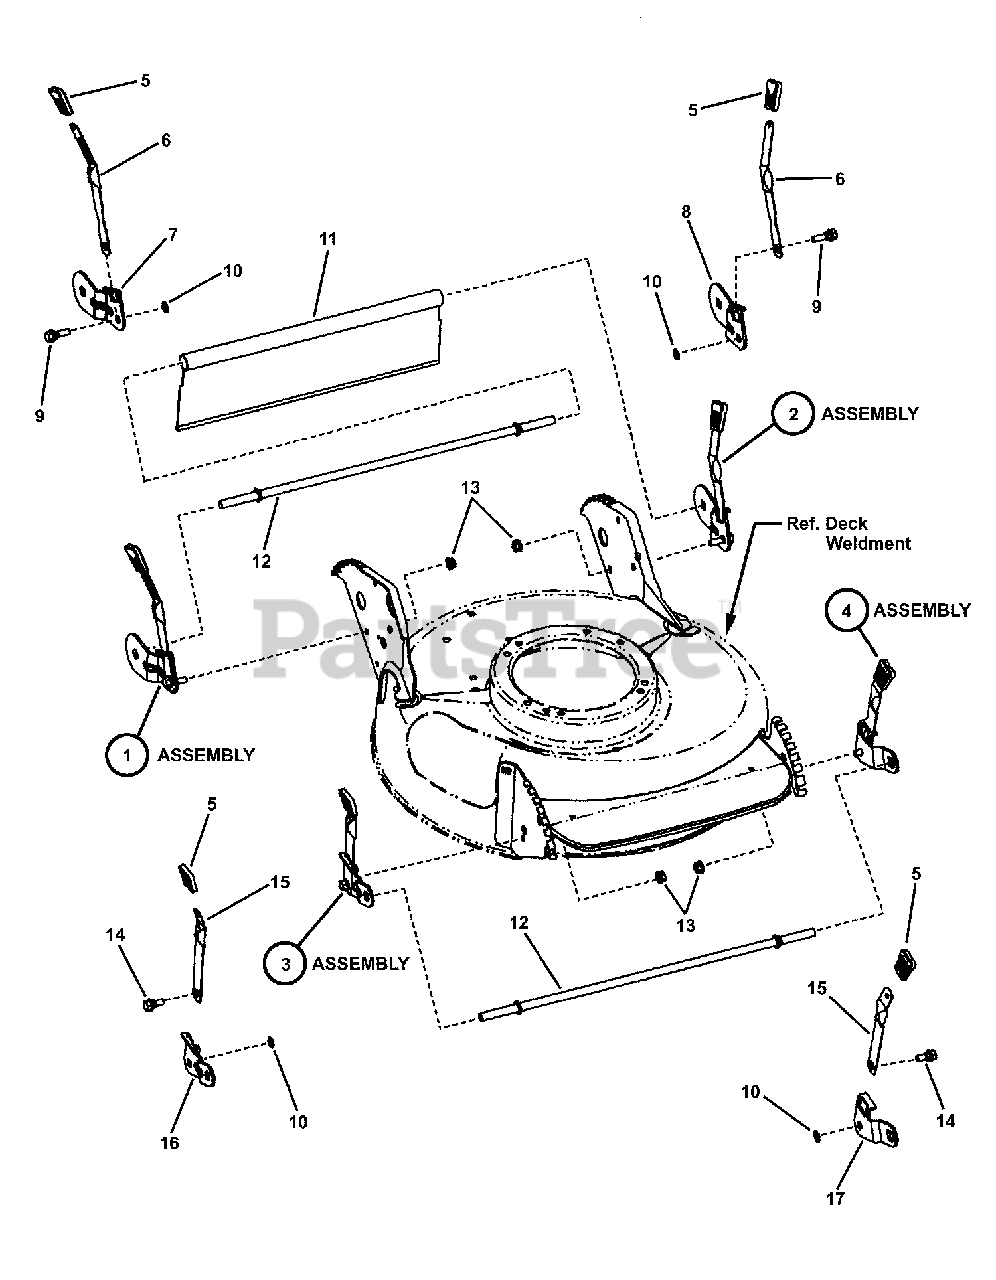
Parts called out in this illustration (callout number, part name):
1	ASSY, Wheel Arm, Right Rear (Push)
2	ASSY, Wheel Arm Left Rear Long (Push)
3	ASSEMBLY, Right Wheel Arm
4	ASSEMBLY, Left Wheel Arm
5	GRIP, Height Latch - Black (1.3" Wide)
6	LATCH, Height Adjusting (long)
7	ARM, Wheel, Right Rear
8	ARM, Wheel, Left Rear
9	BOLT, 5/16-18 x 1" Hex Washer Face Shoulder
10	RETAINER, 5/16" Bolt
11	FOOT GUARD, Long Rear (21 Push)
12	AXLE, 21"
13	NUT, 5/16-18 Hex Flange Lock, GR 5
14	BOLT, 5/16-18 x 3/4" Hex Washer Face Shoulder
15	LATCH, Height
16	WHEEL ARM, R.H. Front (Round Hole)
17	WHEEL ARM, L.H. Front (Square Hole)
